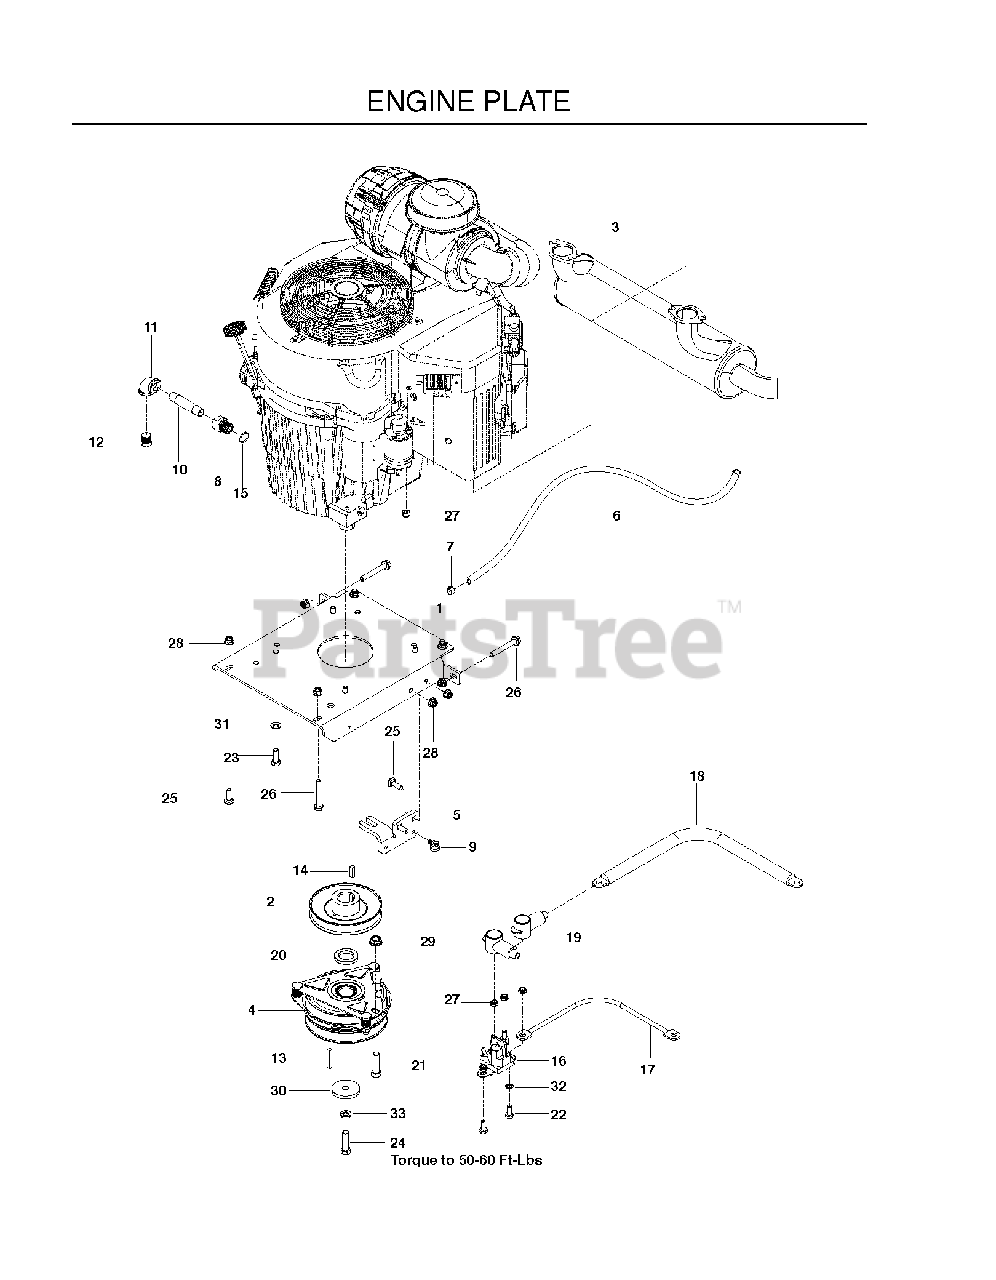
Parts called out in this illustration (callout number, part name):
1	PLATE.ENGINE.BLACK
2	PULLEY, ENGINE
3	MUFFLER.26HP.KAW.FX651V-730V
4	CLUTCH, 150 FT/LBS
5	STOP, CLUTCH, OGURA
6	FUEL LINE 18"
7	HOSE CLAMP
8	ADAPTER, OIL DRAIN
9	TIE WRAP, 8-3/8", W/CLIP
10	PIPE NIPPLE 3/8 X 3
11	90 DEG.ELBOW 3/8NPT
12	PLUG, DRAIN 3/8 NPTF
13	KEY 1/4 SQ X 2
14	KEY 1/4 SQ X 1.0
17	GROUND WIRE (KAW)
18	CABLE POSITIVE
20	SPACER, .25 X 1.135 I.D.
21	HCS 7/16-14 X 1-1/4 GR 5 ZD
22	HCS 1/4C X 5/8
23	HCS 3/8-16X1.GRD.5.ZD
24	HCS 7/16F X 1 1/2
25	RHSNB 5/16C X 1
26	HHFS 5/16-18 X 2.25 GD 5
27	JAM NUT 1/4C (2 2 PW01)
28	5/16-18 NYLOC FLANGE NUT
29	NUT 7/16C WHIZ
30	BLADE WASHER
31	WASHER, 3/8 DISC SPRING SPEC
32	WASHER 1/4 INT TOOTH
33	WASHER 7/16 LOCK
